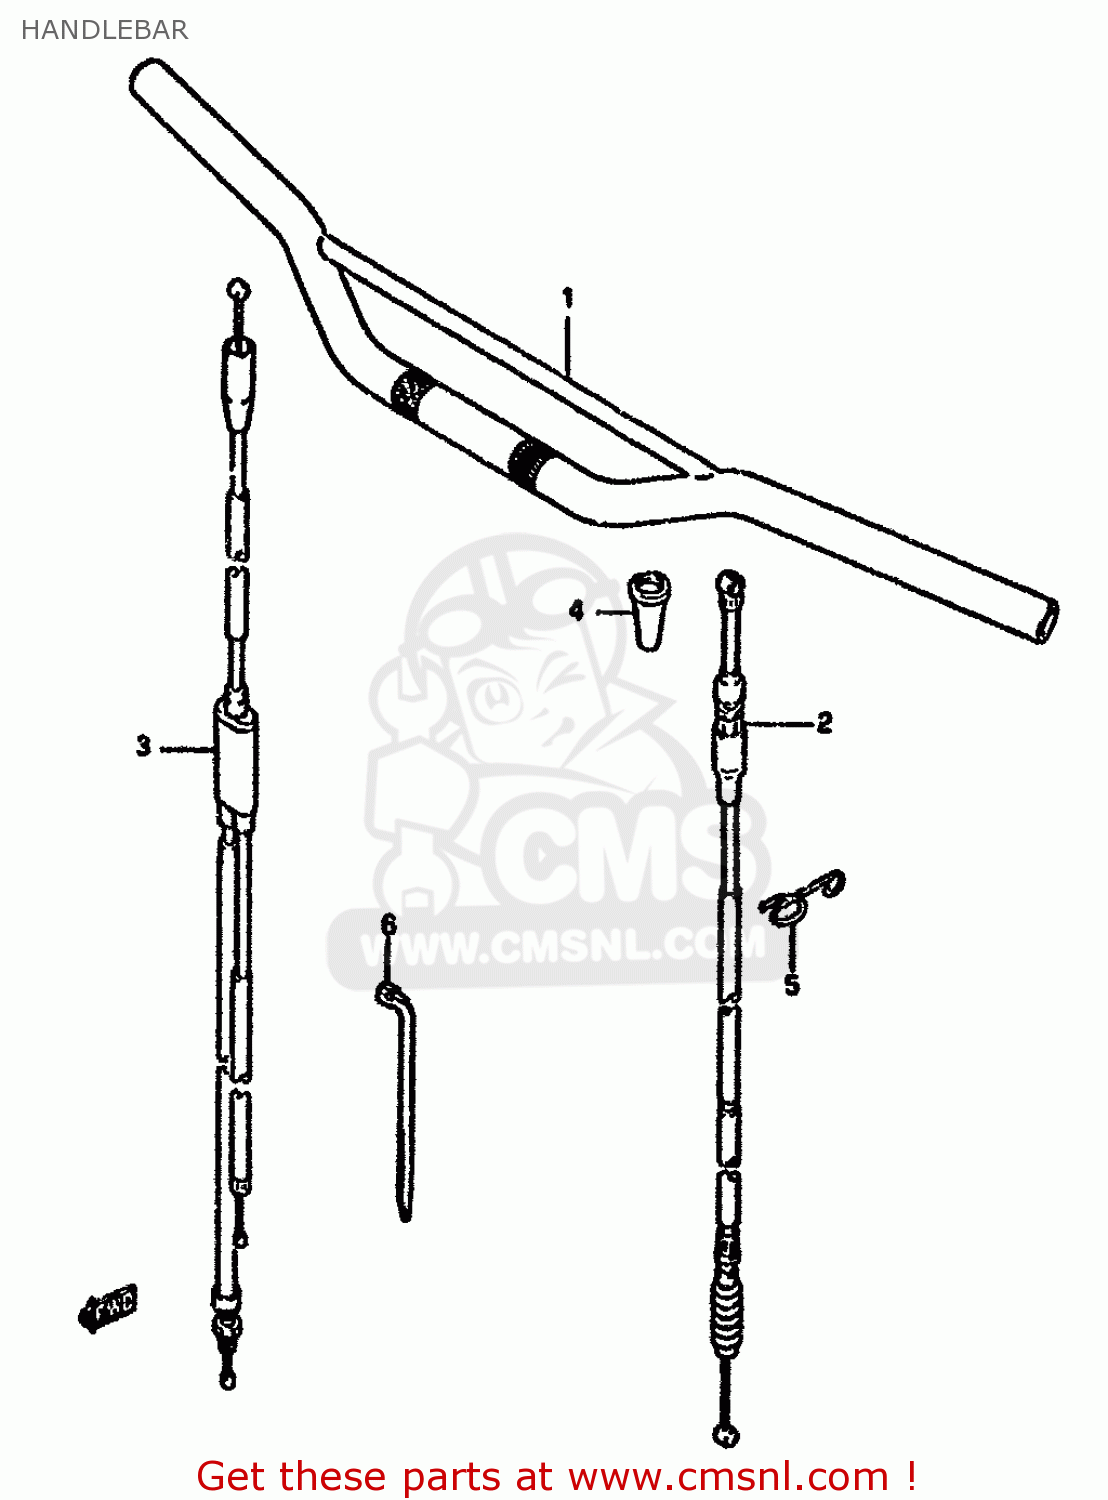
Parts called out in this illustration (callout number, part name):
1	HANDLEBAR
2	CABLE,CLUTCH
3	CABLE ASSY,THROTTLE
4	BOOT,CLUTCH CABLE
5	GUIDE,CLUTCH CABLE
6	CLAMP(L:300)
